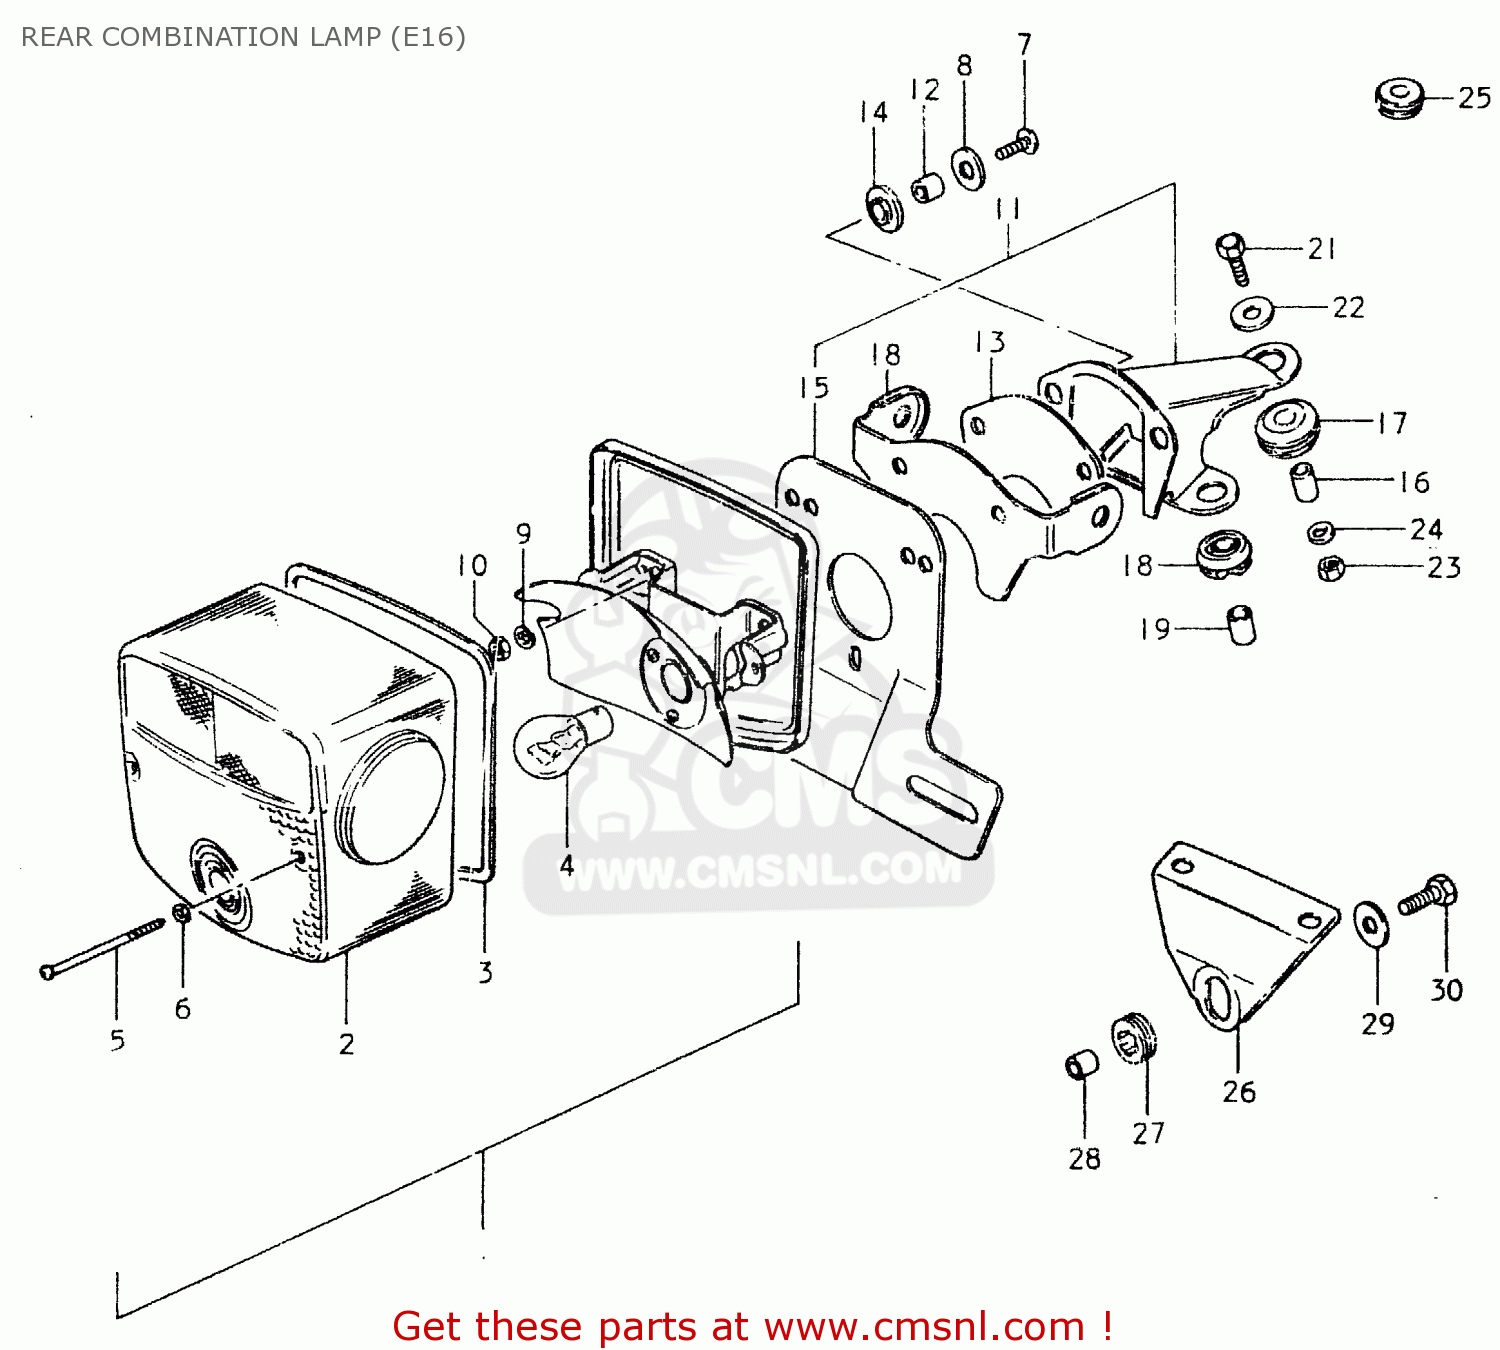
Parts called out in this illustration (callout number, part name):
1	LAMP UNIT, TAIL
2	LENS
3	GASKET (NAS)
4	BULB (6V,21/5W)
5	SCREW (4X55)
6	GASKET (NAS)
7	SCREW
8	WASHER,REAR COMBINATION LAMP
9	NUT
10	LOCK WASHER
11	BRACKET SET
12	SPACER
13	CUSHION
14	CUSHION,REAR COMBINATION LAMP
15	PLATE, LICENCE
16	SPACER
17	CUSHION,REAR COMBINATION LAMP
18	BRACKET, TURN SIGNAL
19	CUSHION,REAR COMBINATION LAMP
20	SPACER
21	BOLT
22	WASHER (6.5X20X1.2)
23	NUT
24	WASHER 6MM
25	GROMMET
26	REINFORCEMENT
27	CUSHION
28	SPACER (6.1X9X9)
29	WASHER (6.5X20X1.2)
30	BOLT, UPPER
